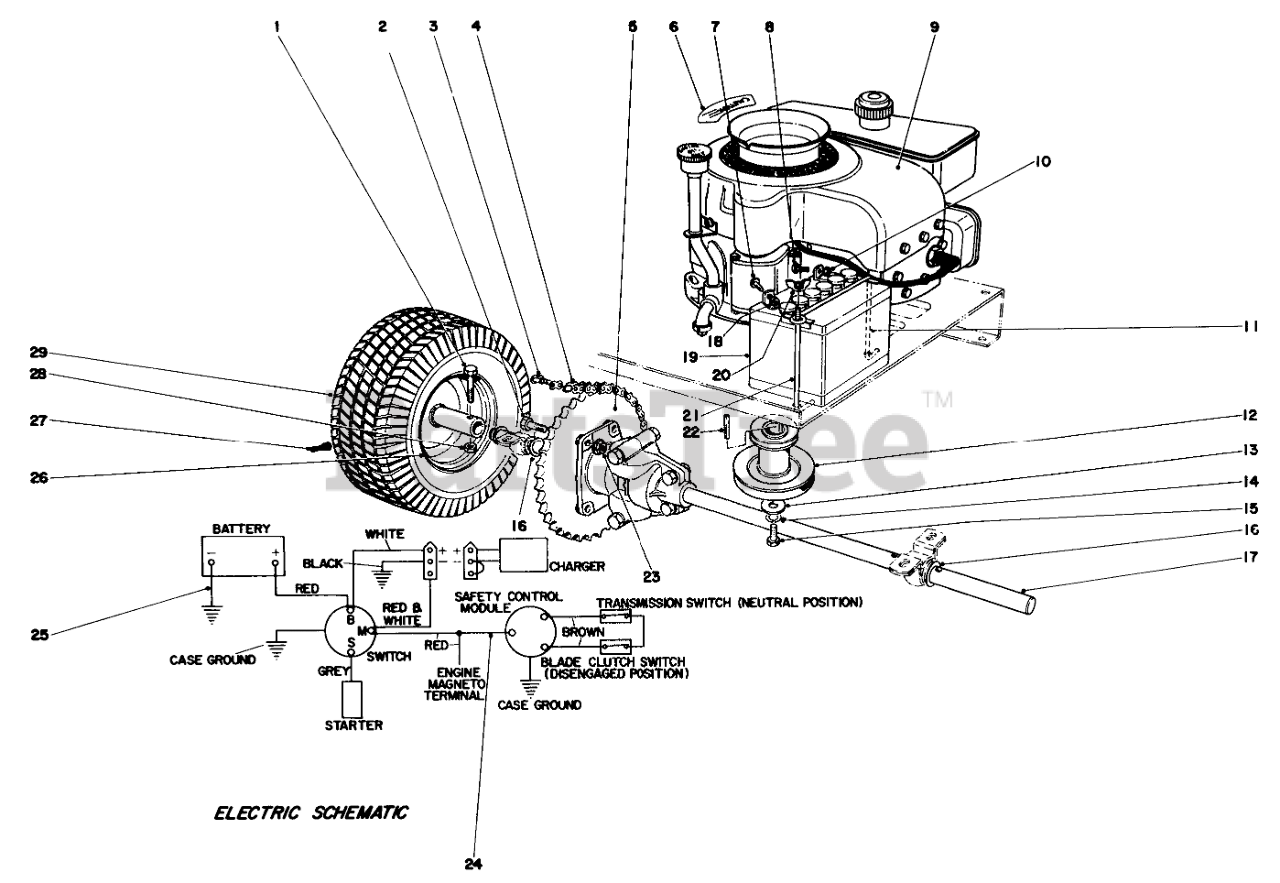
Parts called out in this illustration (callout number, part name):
1	SCREW-HH
2	SCREW-HH
3	LINK-CONNECTING
4	Roller Chain
5	Sprocket
6	Decal
7	SCREW-HH
8	SCREW-HH
9	Engine
10	NUT-HEX
11	PULLEY-IDLER
12	Pulley
13	Washer
14	WASHER-LOCK
15	SCREW-HH
16	WASHER
17	Differential
18	NUT-HEX
19	Battery
20	NUT-WING SPECL
21	ROD-SUPPORT, BATTERY
23	NUT-LOCK, CONE
24	Wiring Harness
25	ENG-GROUND WIRE ASM
27	STEM-VALVE
28	NUT-LOCK, CONE
29	Tire
